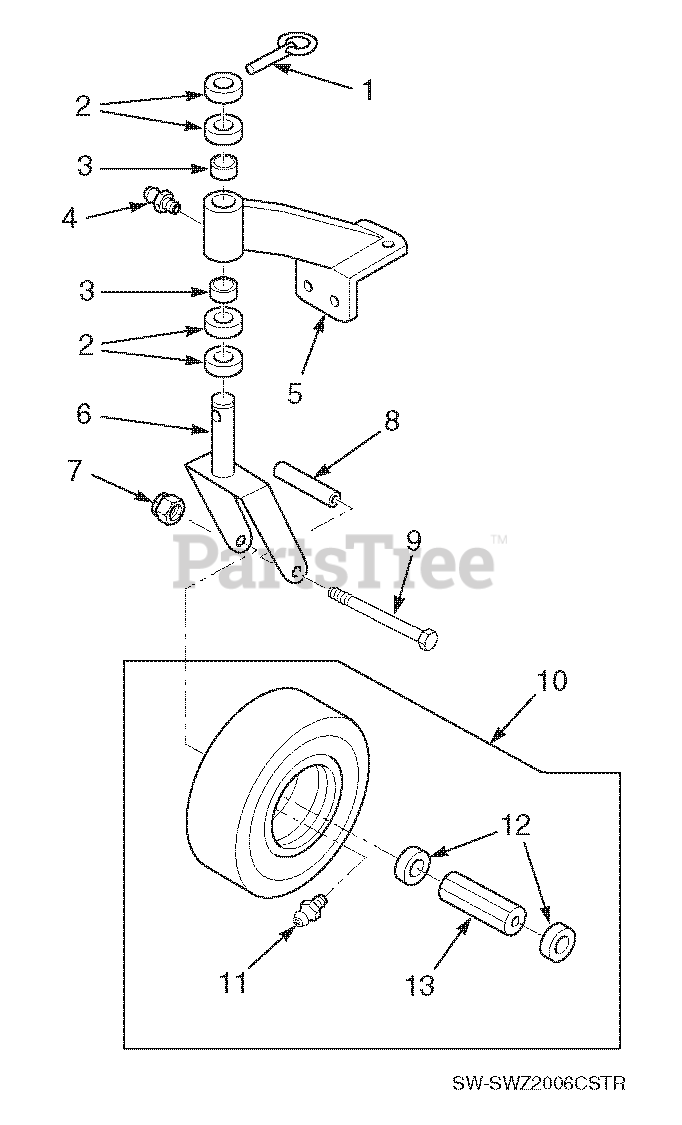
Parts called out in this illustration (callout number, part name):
1	Quick Pin
2	Spacer, Spacer Yoke, 1/2" Long
3	Bronze Bearing
4	Greasing Fitting
5	Support Assembly
6	Caster Yoke
7	Nut, Elastic Stop 1/2-13
8	Sleeve, Caster Wheel Bearing
9	Bolt, Hex Head 1/2-13 x 5-1/2"
10	Flat-Free Tire Assy.
11	Grease Fitting, 45 Degree 1/4-28
12	Retainer, Caster Wheel Bearing
13	Roller Bearing, Caster Wheel
